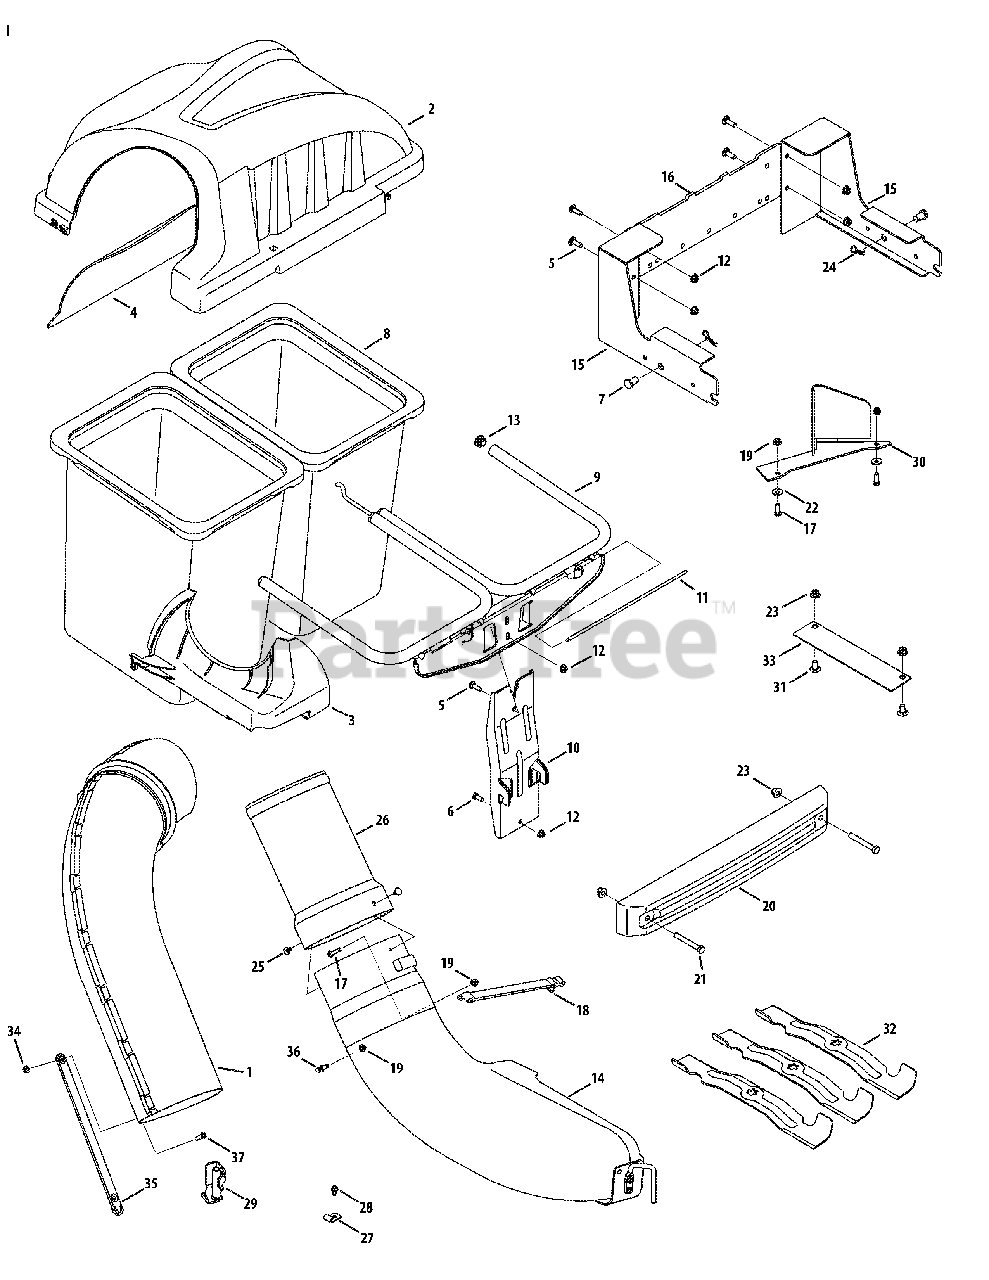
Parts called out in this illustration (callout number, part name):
1	Upper Chute Assembly
2	Twin Bagger Cover Assembly
3	Upper Chute Support
4	Bagger Cover Screen
5	Carriage Screw, 5/16-18 x 1.00"
6	Hex Head Screw, 5/16-18 x .75"
7	Clevis Pin, .50" Dia.
8	Grass-bag Assembly
9	Twin Bag Support Assembly
10	Vertical Support Bracket
11	Cover Hinge Pin
12	Flange Lock Nut, 5/16-18
14	Discharge Chute Elbow
15	RZT Hitch Bracket Kit (RH & LH)
16	Universal Cross Bracket
17	Hex Head Screw, 1/4 - 20 x .75
19	Flange Lock Nut, 1/4 - 20
20	Bagger Weight
21	Hex Head Screw, 3/8 - 16 x 2.75
22	Belleville Washer
23	Flange Lock Nut, 3/8 - 16
24	Cotter Pin, .080 x 1.5625 Internal
25	Ratchet Clip, .250
26	Bagger Chute Adapter, 8 x 13.5
27	Retainer Hook Bracket
28	Self-Tap Screw, 1/4-20 x .500
29	Chute Stop Bracket
30	Deck Baffle, 50"
31	Carriage Bolt, 3/8-16 x 1.00
32	Bagging Blade, 17.90 Lg. Star
33	Chute Discharge Plate
34	Flange Lock Nut, 1/4-20
36	Grass-catcher Pin
37	Machine Screw, 1/4-20
